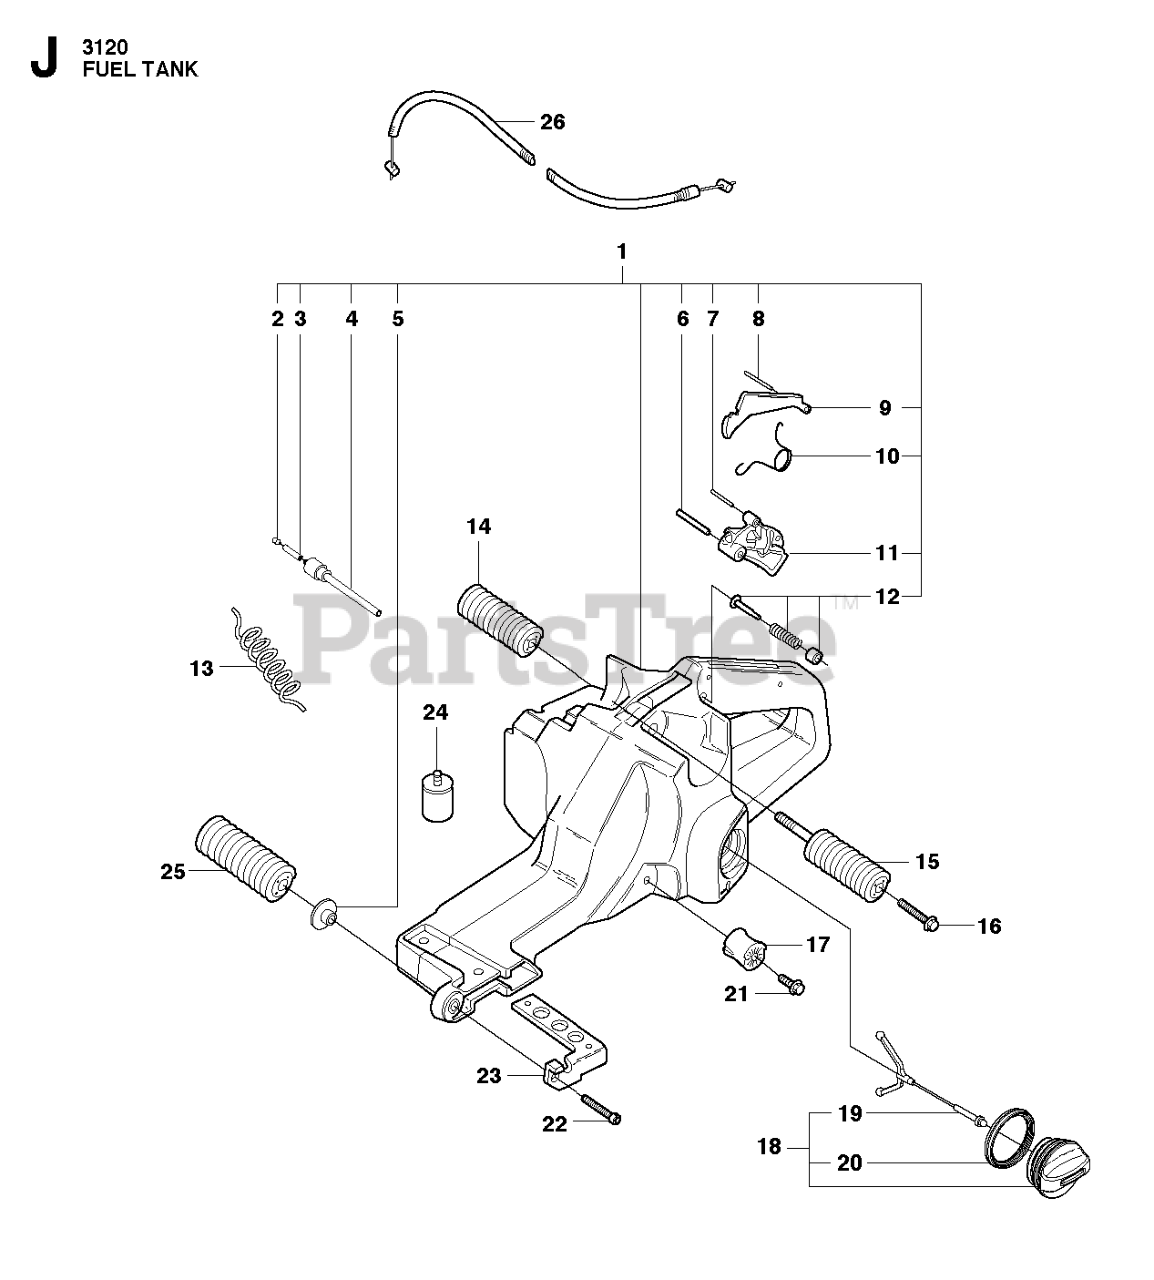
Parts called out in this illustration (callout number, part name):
2	SINTER PLUG
4	TANK VENT
6	PIN 4 X 35
7	PIN 3X25
8	PIN 3X25
9	THROTTLE CATCH
11	THROTTLE LEVER
12	THROTTLE CATCH,KIT
13	FUEL HOSE SPIRAL 300
14	ANTIVIBE ELEMENT
15	ANTIVIBE ELEMENT
16	SCREW MC6S 6X16
17	ANTIVIBE ELEMENT
21	SCREW MC6S 5X12
22	SCREW MC6S 5X30
24	FUEL FILTER
25	ANTIVIBE ELEMENT
26	THROTTLE WIR KPL
